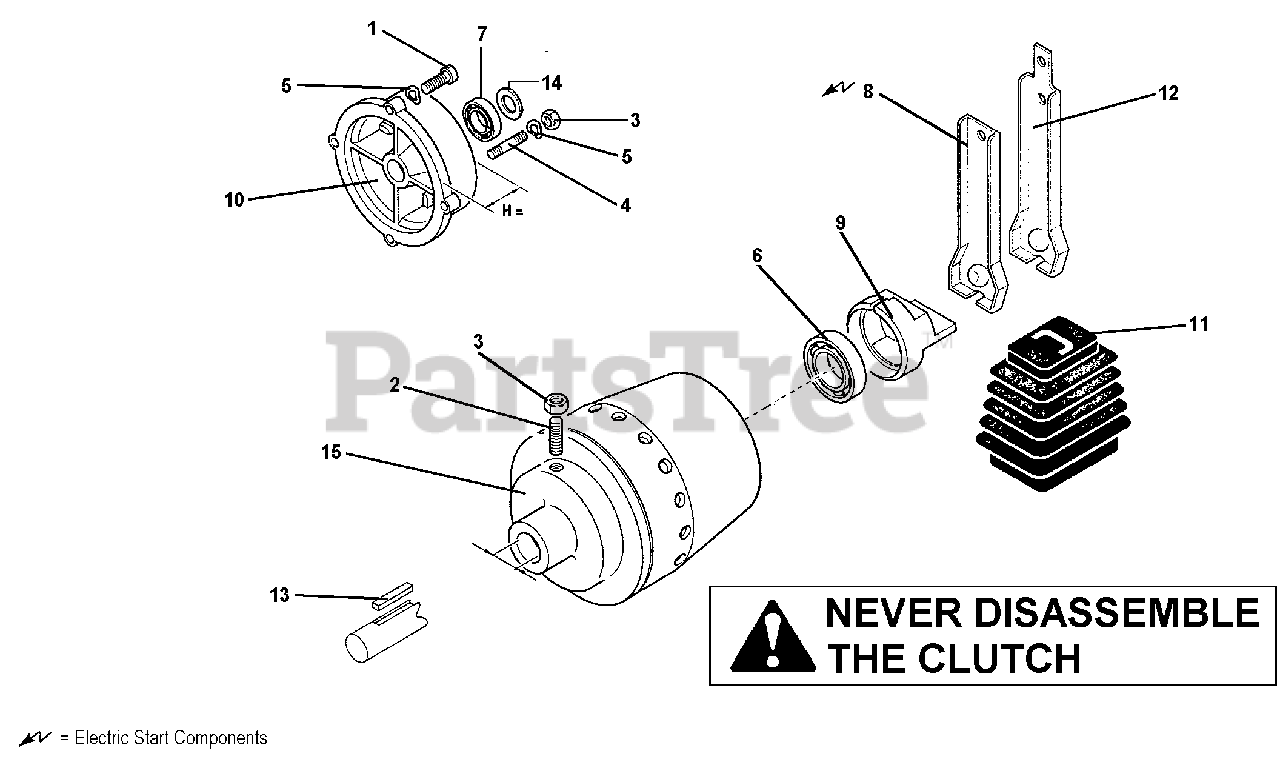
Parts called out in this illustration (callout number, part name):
1	SCREW 3/8X1"
2	SCREW M8X30
4	STUD,M8X40X14X14
5	WASHER, WAVE
6	BEARING,M17X40X12
7	BEARING,M30X55X15
8	CLUTCH LEVER, ELECTRIC START
9	CONE PUSHER
11	BOOT, ELECTRIC START
12	CLUTCH LEVER, RECOIL START
13	KEY WOODRUFF
15	CLUTCH, 12HP KOHLER CS PRO
